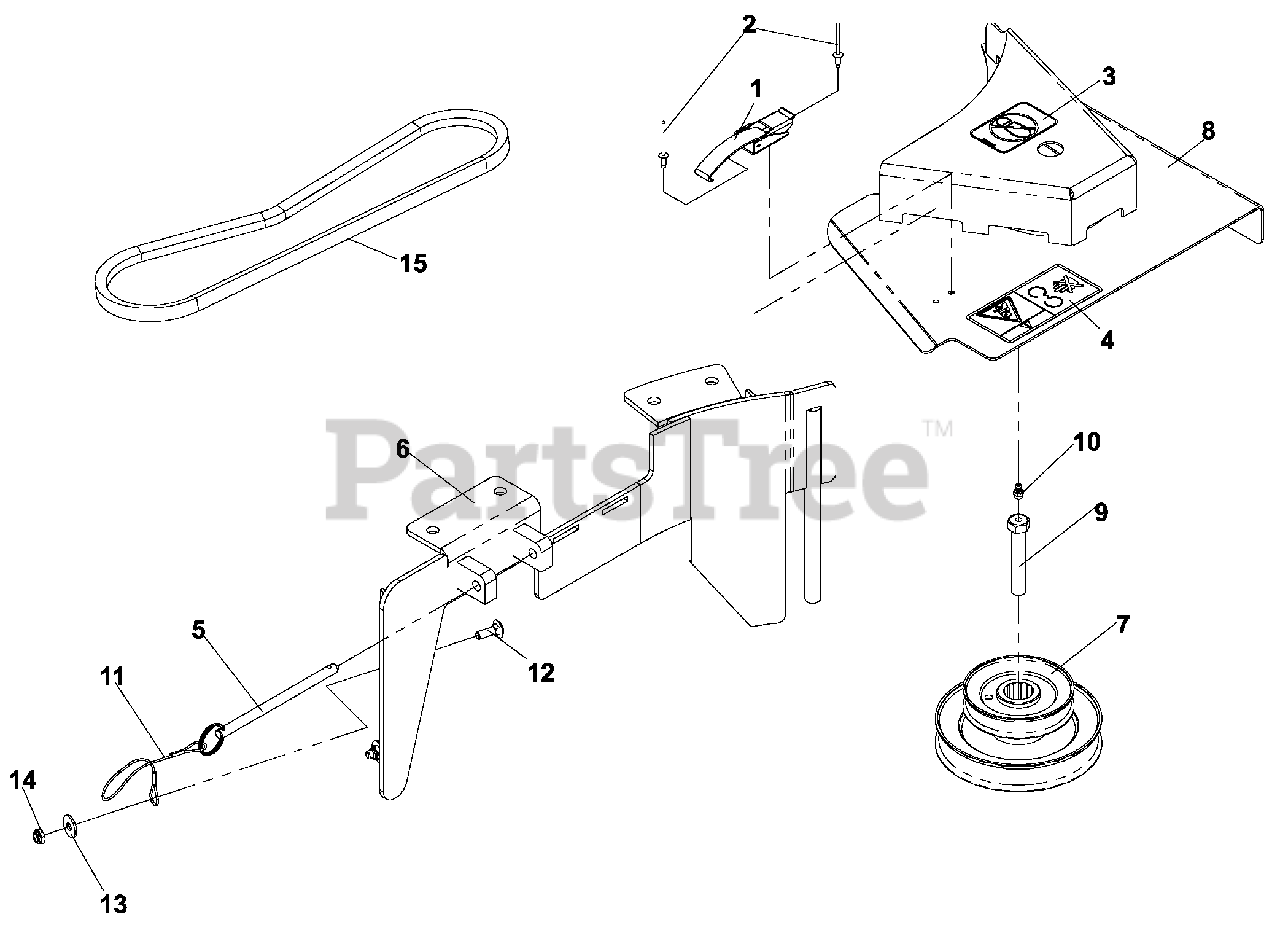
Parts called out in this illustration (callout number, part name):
1	DRAW LATCH
2	RIVET, BLIND, DOME STYLE, 5/32 DIA.
3	DECAL, NO STEP
4	DECAL, DANGER BELT DRIVES
6	BLOWER DECK PLATE, 52
7	PULLEY, STACKED DOUBLE, 52
8	BELT SHIELD W/DECALS & LATCH, 52
9	HCS, 7/16-20 X 2 1/2, GR5, SPEC.
10	ZERK
12	RHSNB, 1/4-20 X 3/4, GR2
13	WASHER, 1/4
14	NUT, 1/4C, THIN NYLOC
